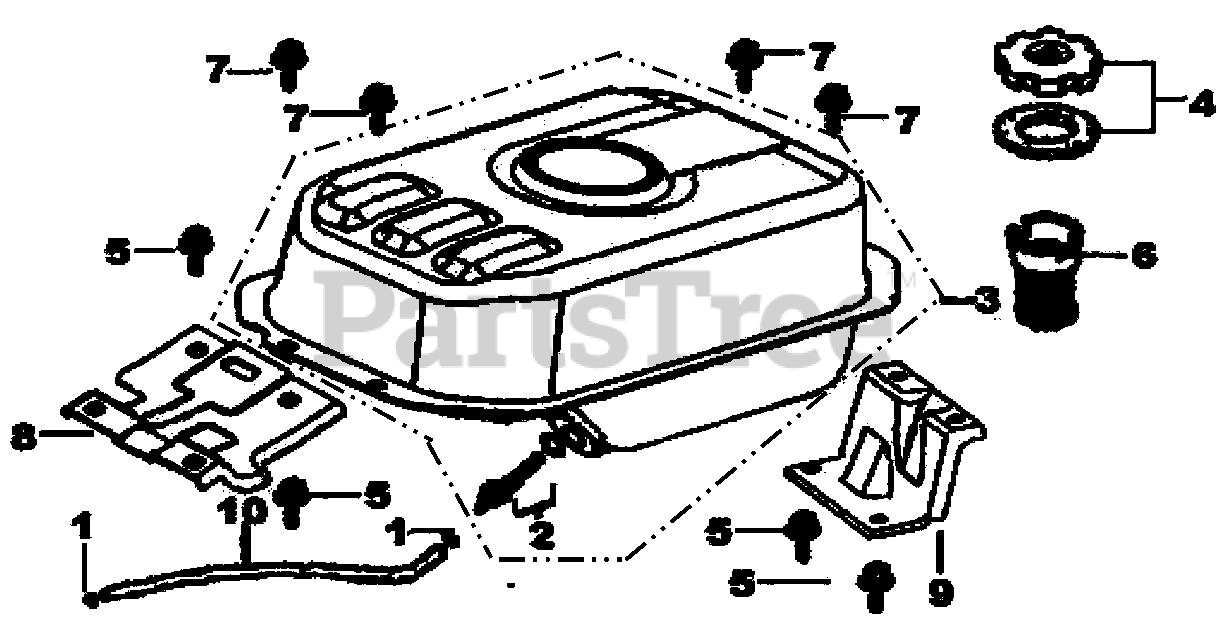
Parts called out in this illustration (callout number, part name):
1	LOOP, TUBE
2	JOINT ASSYL, FUEL TANK
3	TANK, COMP., FUEL
4	CAP COMP., FUEL FILLER
5	BOLT, FLANGE
6	FILTER, FUEL
7	BOLT, FLANGE
8	HOLDER FUEL TANK
9	HOLDER FUEL TANK
10	TUBE, FUEL
